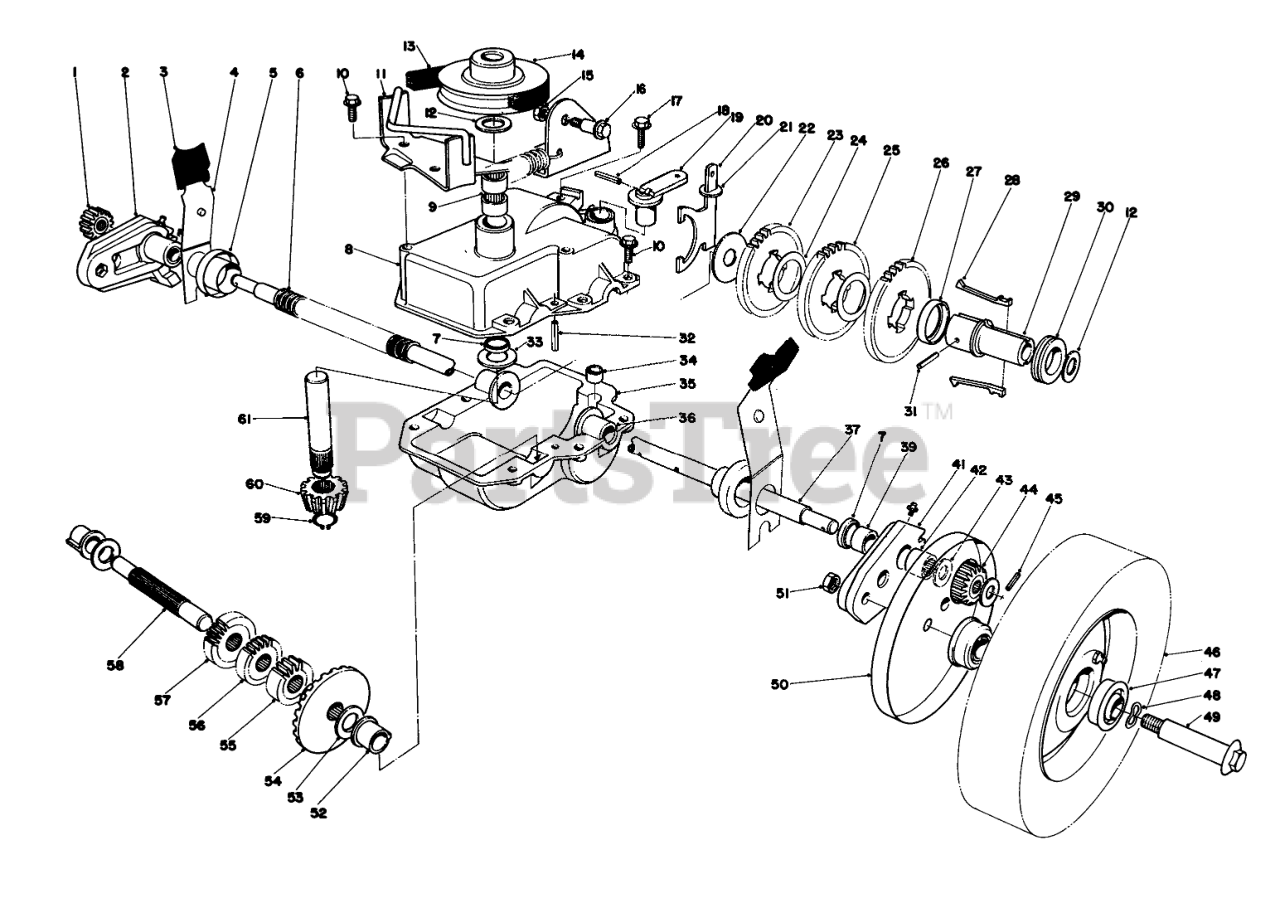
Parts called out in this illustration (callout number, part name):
1	Pinion Gear
2	Pivot Arm R.H. (Incl. Ref. #7, 39, & 42)
3	KNOB-ARM
4	Spring Arm
5	End Cap
6	CONDUIT-CONVOLUTED, SPLIT
7	Seal
8	Case Upper
9	Bearing
10	Screw
11	Belt Guide Bracket
12	WASHER-PLAIN
13	V-BELT
14	Pulley
15	NUT-HEX, SIDE DEFORM
16	Shoulder Bolt
17	SCREW-HWHTF
18	PIN-COIL
19	LEVER-SHIFT
20	Shift Yoke
21	Yoke Washer
22	WASHER
23	Gear 38T
24	WASHER
25	Gear
26	Gear
27	Key Retainer
28	KEY-SHIFT
29	Sleeve
30	COLLAR-SHIFT
31	COIL PIN
32	ROLL PIN 3/16 X 1 IN
33	Thrust Washer
34	BUSHING-YOKE
35	LOWER GEAR CASE CAST
36	Bushing
37	OUTPUT SHAFT
39	Bushing
41	Pivot Arm L.H. (Incl. Ref. #7, 39, & 42)
42	Needle Baring
43	WASHER
44	Pinion Gear
45	Pin
46	WHEEL ASM
47	BEARING-BALL
48	SPRING WASHER
49	WHEEL BOLT
50	Cover-Wheel
51	Nut
52	Botching Shaft
53	WASHER-THRUST
54	Bevel Gear
57	Gear 18T
58	Short Shaft
59	RING-RETAINING
60	Pinion Bevel
61	Input Shaft & Pulley Assy. (Incl. Ref. #14)
